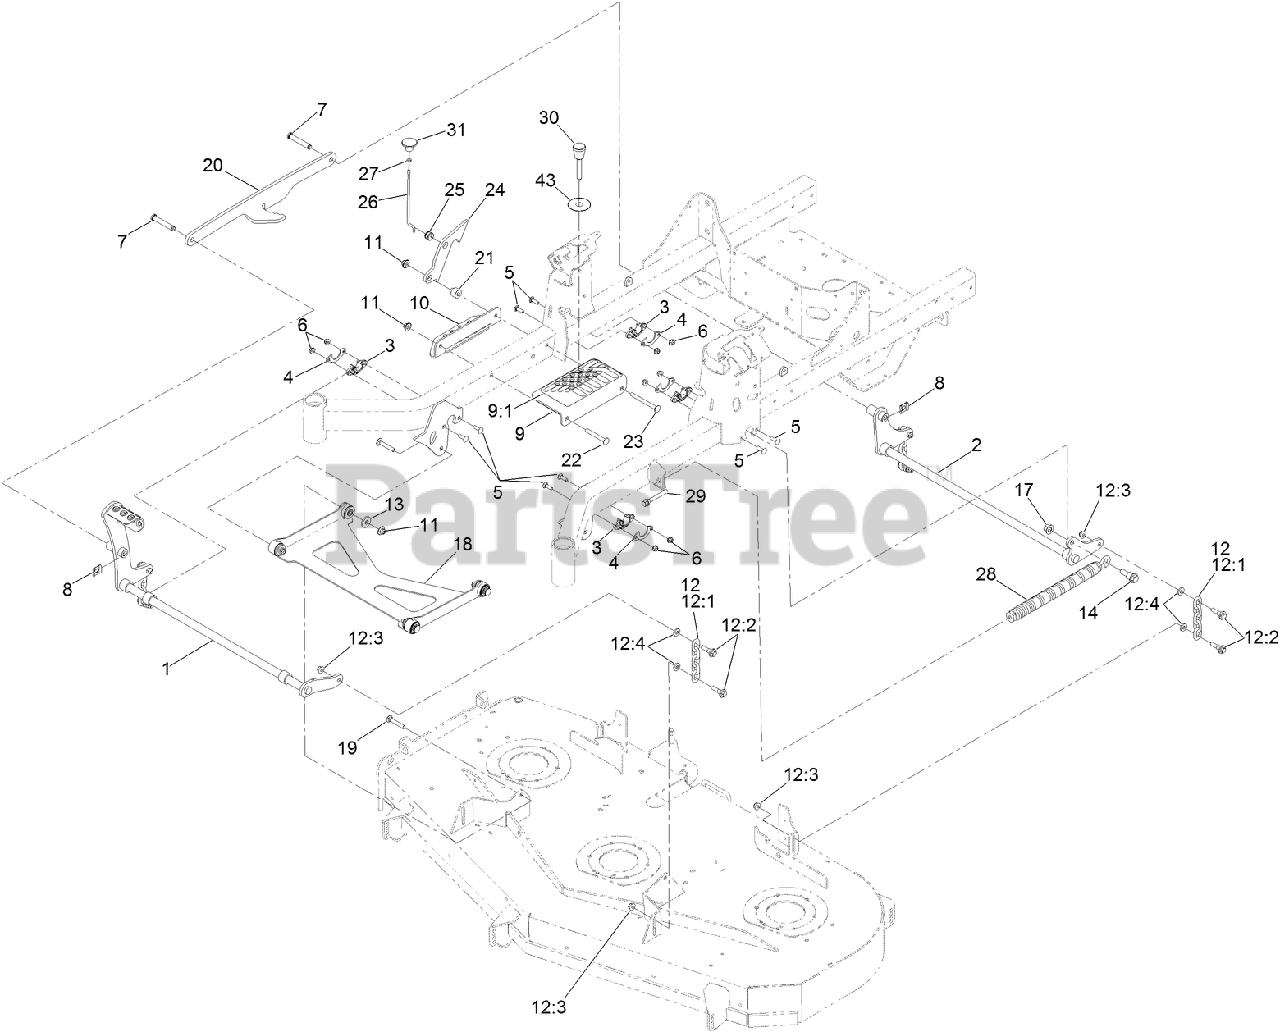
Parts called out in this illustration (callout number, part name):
1	SHAFT-LIFT, DECK
2	SHAFT-LIFT, DECK (REAR)
3	BUSHING-FLANGE
4	GUSSET-LIFT, DECK
5	SCREW-CARR
6	NUT-HF, NI
7	PIN-CLEVIS
8	CLIP-PIN
9	BRACKET ASM
9:1	DECAL-HOC
10	ANGLE-HOC, LOWER
11	NUT-FLANGE, NI
12	DECK CHAIN ASM
12:1	CHAIN-LIFT, DECK
12:2	BOLT-SHOULDER
12:3	NUT-HF, NI
12:4	SPACER
13	WASHER
14	SCREW-SHOULDER, HHF
17	NUT-LOCK
18	DECK STRUT ASM
19	SCREW-CARR
20	LINK-LIFT
21	SPACER-STEPPED
22	SCREW-CARR
23	SCREW-CARR
24	PLATE-LOCK, TRANSPORT
25	GROMMET
26	ROD-LOCK, TRANSPORT
27	NUT-JAM
28	SPRING-EXTENSION
29	BOLT-SHOULDER
30	PIN-HOC
43	TAG-RETENTION, MAGNETIC
